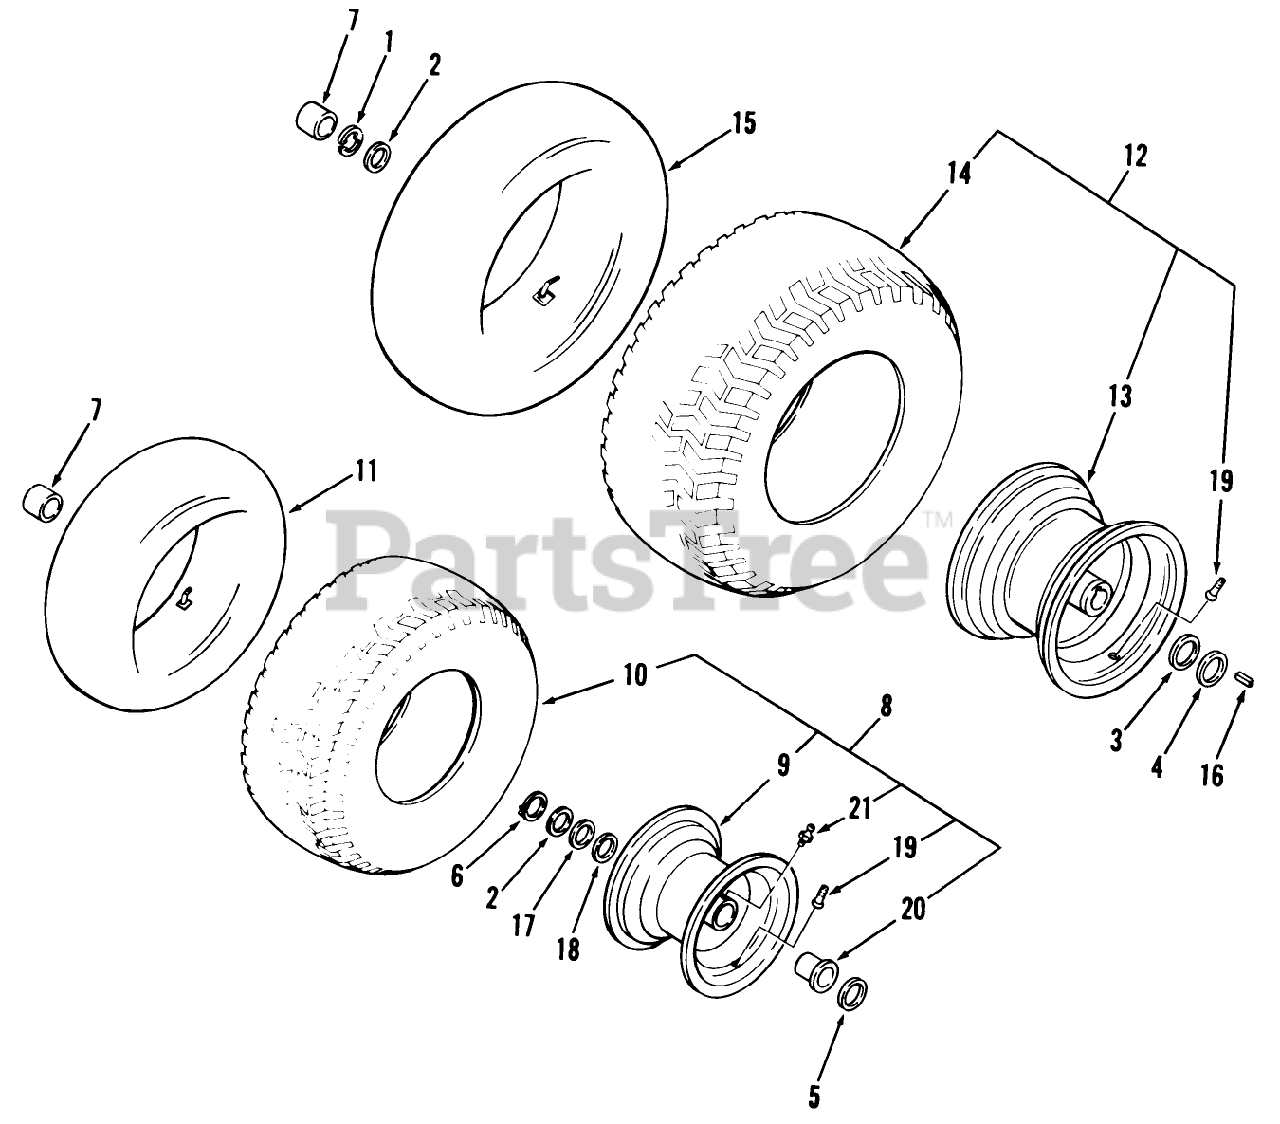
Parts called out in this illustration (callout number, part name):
2	WASHER
3	WASHER-SHIM
4	WASHER
14	TIRE 18 X 9.50-8
16	SQ KEY
17	WASHER
18	WASHER-SHIM
19	VALVE
20	BUSHING-FLANGED
